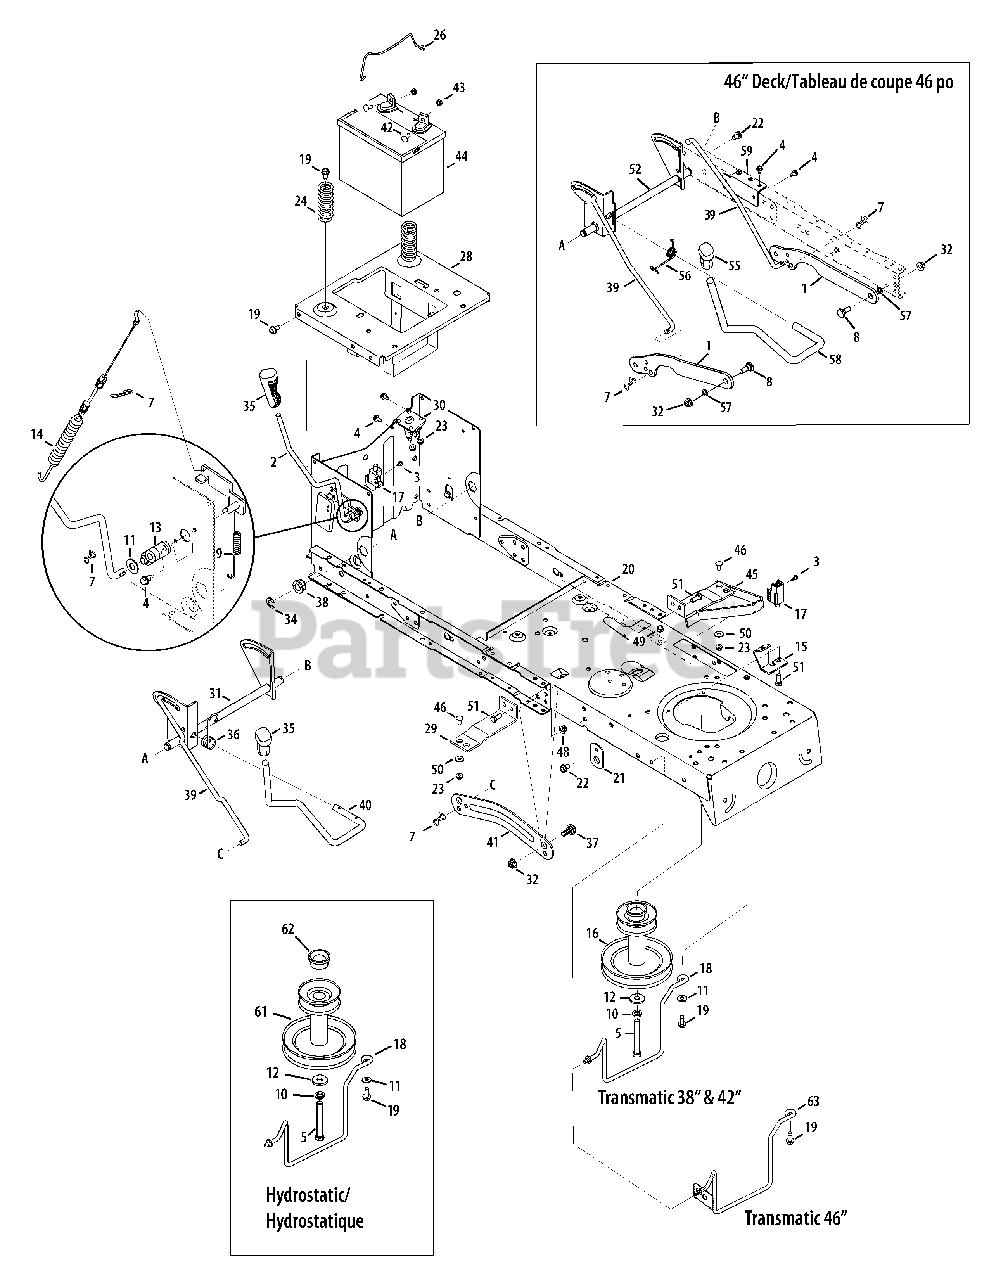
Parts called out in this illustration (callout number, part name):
3	Shoulder Screw #10-16 x .50" Lg.
4	Hex Wash S-Tapp Screw 1/4-20 x .50
5	Hex Hd. Cap Screw. 7/16-20 x 3.25 Gr. 5 (38/42")
5	Hex Hd. Cap Screw. 7/16-20 x 2.75 Gr. 5 (46")
7	Bow Tie Cotter Pin
8	Shoulder Screw .5 x .270 : 3/8-16
9	Extension Spring
10	Lockwasher 7/16 ID
11	Flat Washer .385 ID x .87 OD x .06
12	Flat Washer .450 x 1.25 x .164
13	PTO Bearing
14	Deck Engagement Cable
16	Engine Pulley 3.39 x 6.12 dia. (38/42")
16	Engine Pulley 3.39 x 6.12 dia. (46")
17	Interlock Switch
18	Belt Keeper Rod (38" Deck)
18	Belt Keeper Rod (42" Deck)
19	S-Tapp Screw 5/16-18 x .75
22	Hex Wash HD TT Screw 5/16-18 x .625
23	Hex L-Flanged Nut 1/4-20 Gr. F, Nylon
24	Compression Spring 1.28 x 3.125
26	Battery Hold Down Rod
28	Seat Frame Bracket
30	Solenoid
32	Flange Lock-Nut 3/8-16 Gr. F, Nylon
34	"E" Ring .625 Dia.
35	Handle Grip
36	Torsion Spring (38" & 42")
37	Shoulder Screw .625 x .175, 3/8-16
38	Hex Flange Bearing .630 ID
39	Lift Rod
40	Deck Lift Handle(38"")
40	Deck Lift Handle(42")
42	Hex Flg. Screw. 1/4-20 x .75 Gr. 5
43	Sems Hex Nut 1/4-20
44	Battery 245 CCA (Dry)
46	Carriage Bolt 1/4-20 x .62
48	Hex L-Flg Nut 5/16-18 Gr. F, Nylon
49	Hex L-Nut 5/16-18
50	Flat Washer .28 x .74 x .063
51	Hex Screw 5/16-18 x .75
52	Lift Shaft (46" only)
56	Torsion Spring (46")
57	Flat Washer .395 x .62 x .063
58	Deck Lift Handle (46")
59	Brace Bracket
61	Engine Pulley 3.39 x 6.12 dia. (38/42")
61	Engine Pulley 3.39 x 6.12 dia. (46")
62	Spacer 1.0 x 1.4 x .825
63	Belt Keeper Rod (46" Deck)
